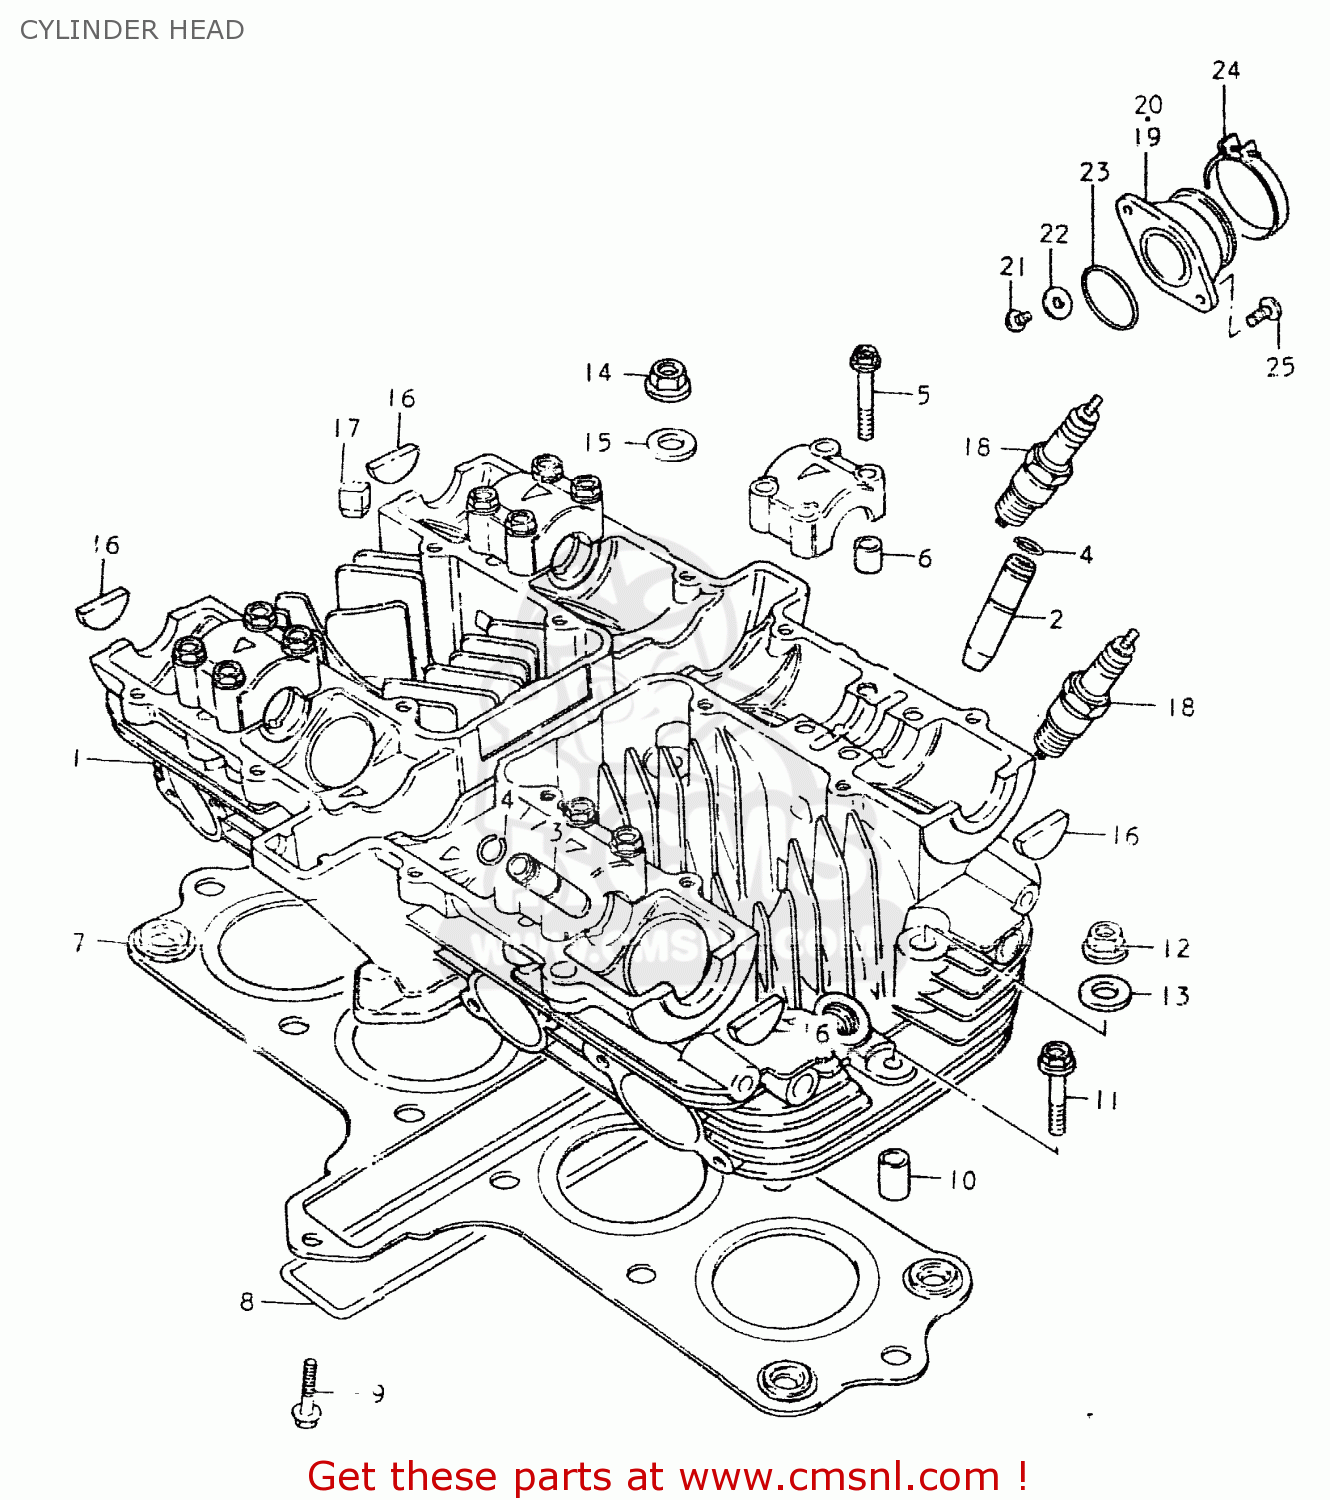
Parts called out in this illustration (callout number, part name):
1	HEAD ASSEMBLY,CYLINDER
2	GUIDE,VALVE
3	GUIDE,EXHAUST VALVE
4	RING,SNAP
5	BOLT(6X39)
6	PIN(6.2X8X11)
7	GASKET,CYLINDER HEAD (MCA)
8	O RING(D:3,ID:26X157)
9	BOLT
10	PIN
11	BOLT,UNDER
12	NUT
13	GASKET (NAS)
14	NUT
15	WASHER(8.5X19X2.3)
16	PLUG
17	PAD
18	SPARK PLUG
19	PIPE,INTAKE,R
20	PIPE,INTAKE,L
21	BOLT
22	GASKET(5.3X9.3X1.2) (NAS)
23	O-RING
24	CLAMP
25	SCREW
